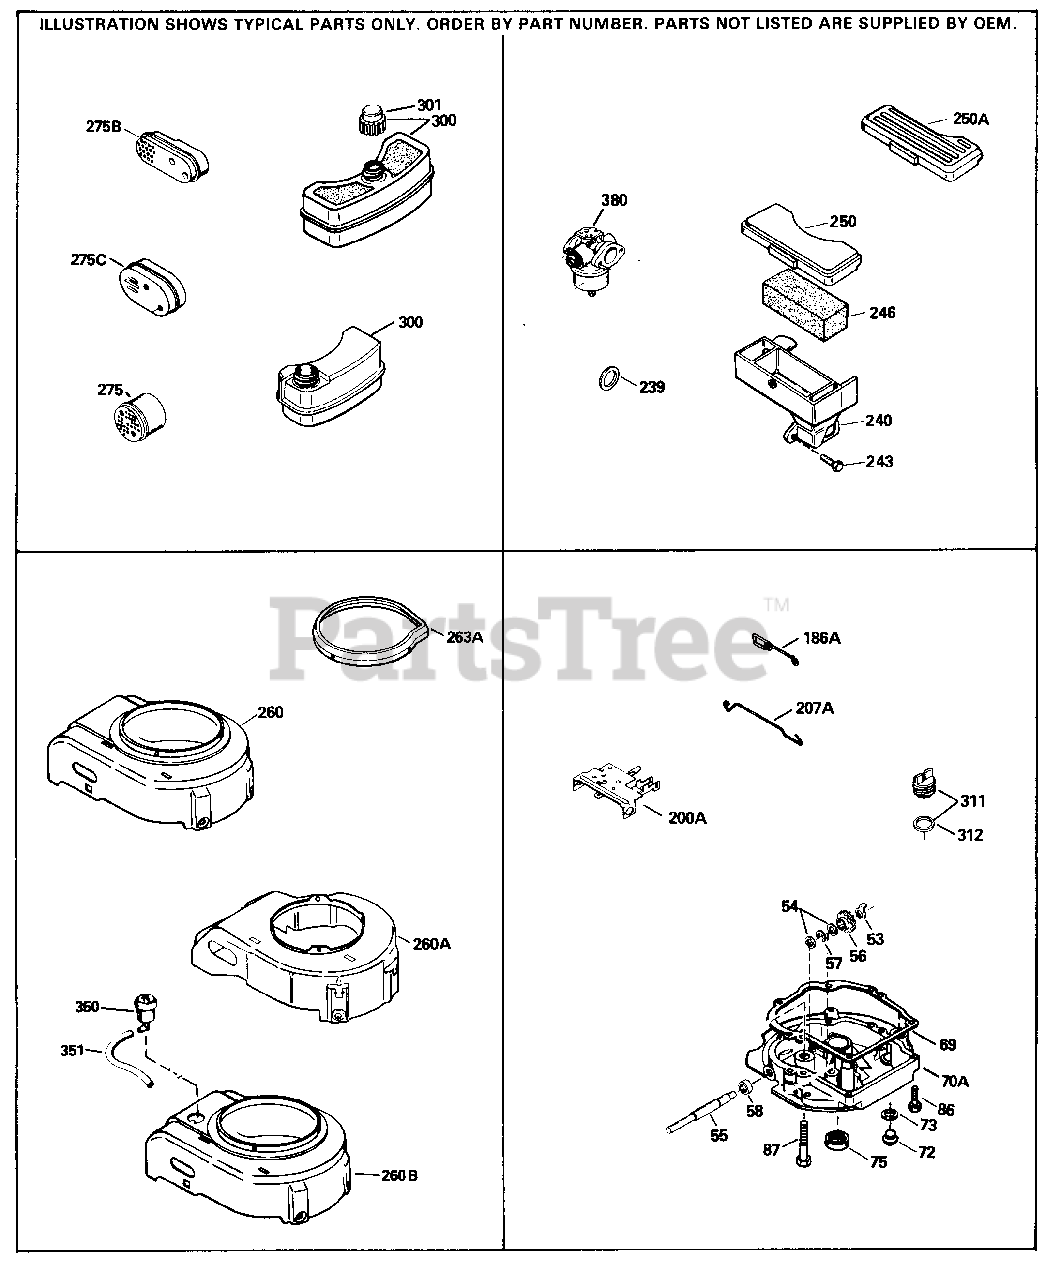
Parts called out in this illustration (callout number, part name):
12A	Breather Cover & Tube
69	Mounting Flange Gasket
72	Oil Drain Plug
75	Oil Seal
86	Screw, 1/4-20 x 1-1/4"
238	Screw, 10-32 x 43/64"
239	* Air Cleaner Gasket
239B	Air Cleaner Seal
240	Air Cleaner Body (Incl. 239)
242	Air Cleaner Base
243	Screw, M-5 x 0.8-6g x 2-7/16"
243B	Square Nut M-5 x 0.8-6h
245B	Air Filter
250	Air Cleaner Cover
260	Blower Housing
275	Muffler (Incl. 277)
298	Screw, 10-32 x 35/64"
300	Fuel Tank (Incl. 292 & 301)
301	Fuel Cap (Red)
370A	Lubrication Decal
380	Carburetor (Incl. 184)
416	Spark Arrestor Kit (Incl. 417) Option al
417	Screw, 8-32 x 3/8" (Optional)
